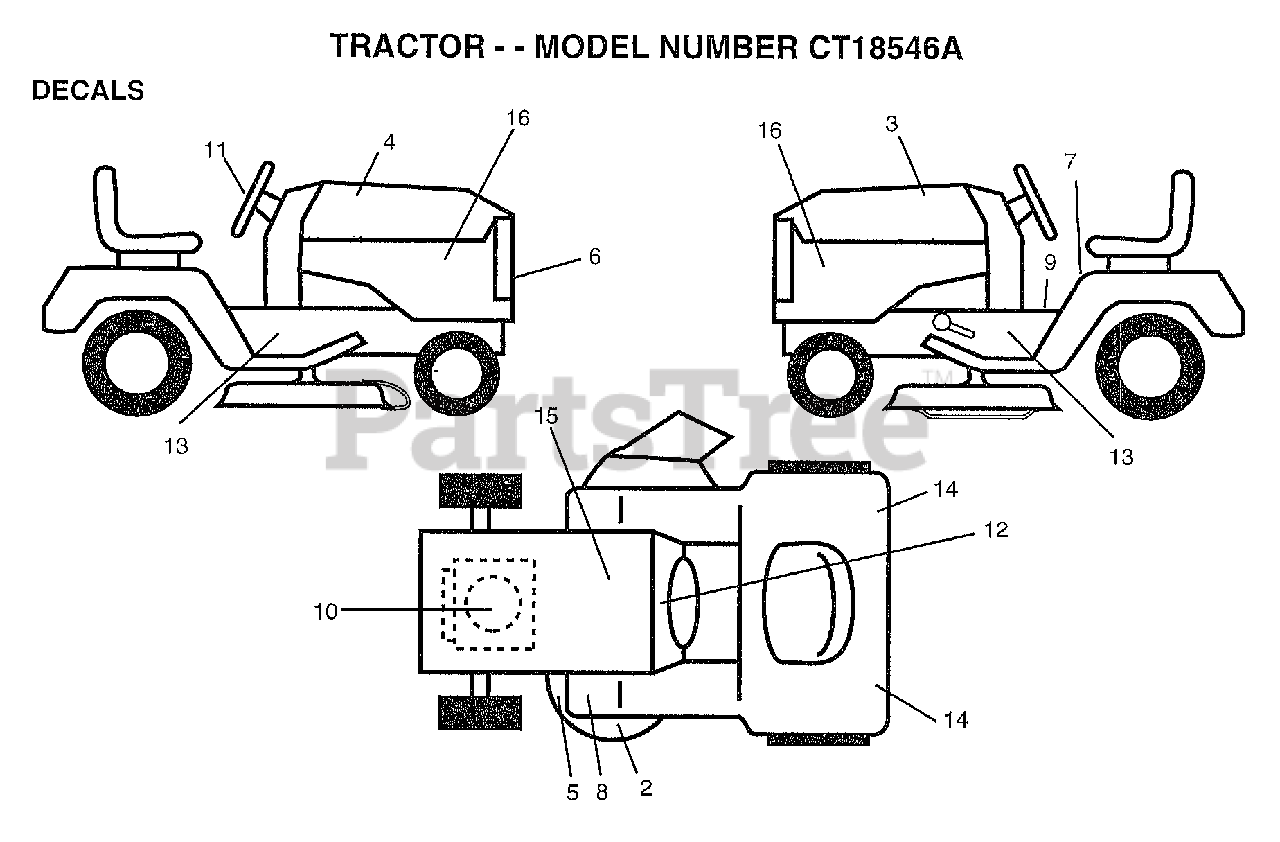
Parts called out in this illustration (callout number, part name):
2	"DECAL,ENVIRO DECK"
3	"DECAL HOOD,LH"
4	DECAL HOOD RH
5	"DECAL.V.BELT.44"""
6	DECAL GRILLE
7	"DECAL DANGER,FEND"
9	DECAL BRAK PARK
10	DECAL, HP, ENGINE
11	DECAL INST STG WH
12	"DECAL-OPER,GEAR D"
13	DECAL CHASSIS
14	REFLECTOR-TAIL YT
15	DECAL.BATRY.3-3908
16	"DECAL PANEL,SIDE"
